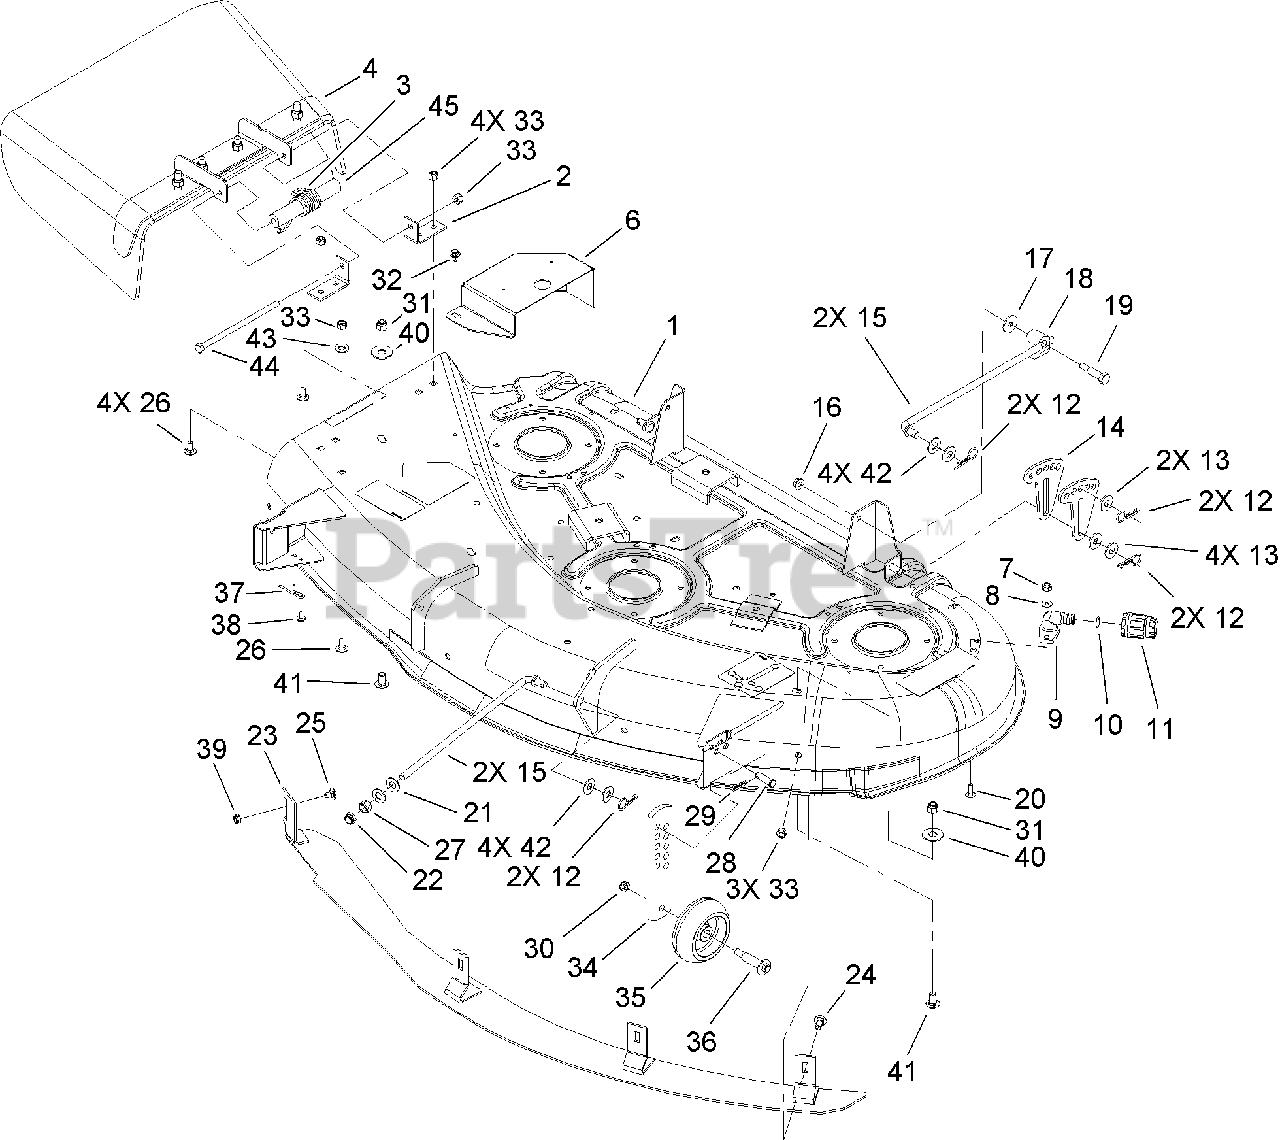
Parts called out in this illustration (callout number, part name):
1	44 INCH DECK ASM
2	BRACKET-PIVOT, DEFLECTOR
3	SPRING-TORSION
4	DEFLECTOR ASM
6	COVER-BELT, RH
7	NUT-LOCK, NI
8	WASHER-FLAT
9	FITTING-WASHOUT
11	CONNECTOR-HOSE
12	PIN-HAIR
13	WASHER-HARDENED
14	LINK-ADJUSTING, HOC
15	ROD-HANGER
17	WASHER-PIVOT
18	TRUNNION-HOC
19	BOLT-SHOULDER
20	SCREW-CARR
21	WASHER-FLAT
22	NUT-LOCK, NI
24	BOLT-CARR
25	SCREW-CARR
26	SCREW-CARR
27	NUT-HEX
28	PIN-CLEVIS
29	PIN-HAIR
30	NUT-LOCK, NI
31	NUT-LOCK, NI
32	SCREW-HHF
33	NUT-LOCK, NI
34	PLATE-GAGE, WHEEL
35	WHEEL-GAGE
36	BOLT-WHEEL
37	SPRING-GAGE, WHEEL
39	NUT-LOCK, NI
40	WASHER-FLAT
41	SCREW-CARR
42	WASHER-FLAT
43	WASHER-FLAT
45	SPACER-DEFLECTOR
